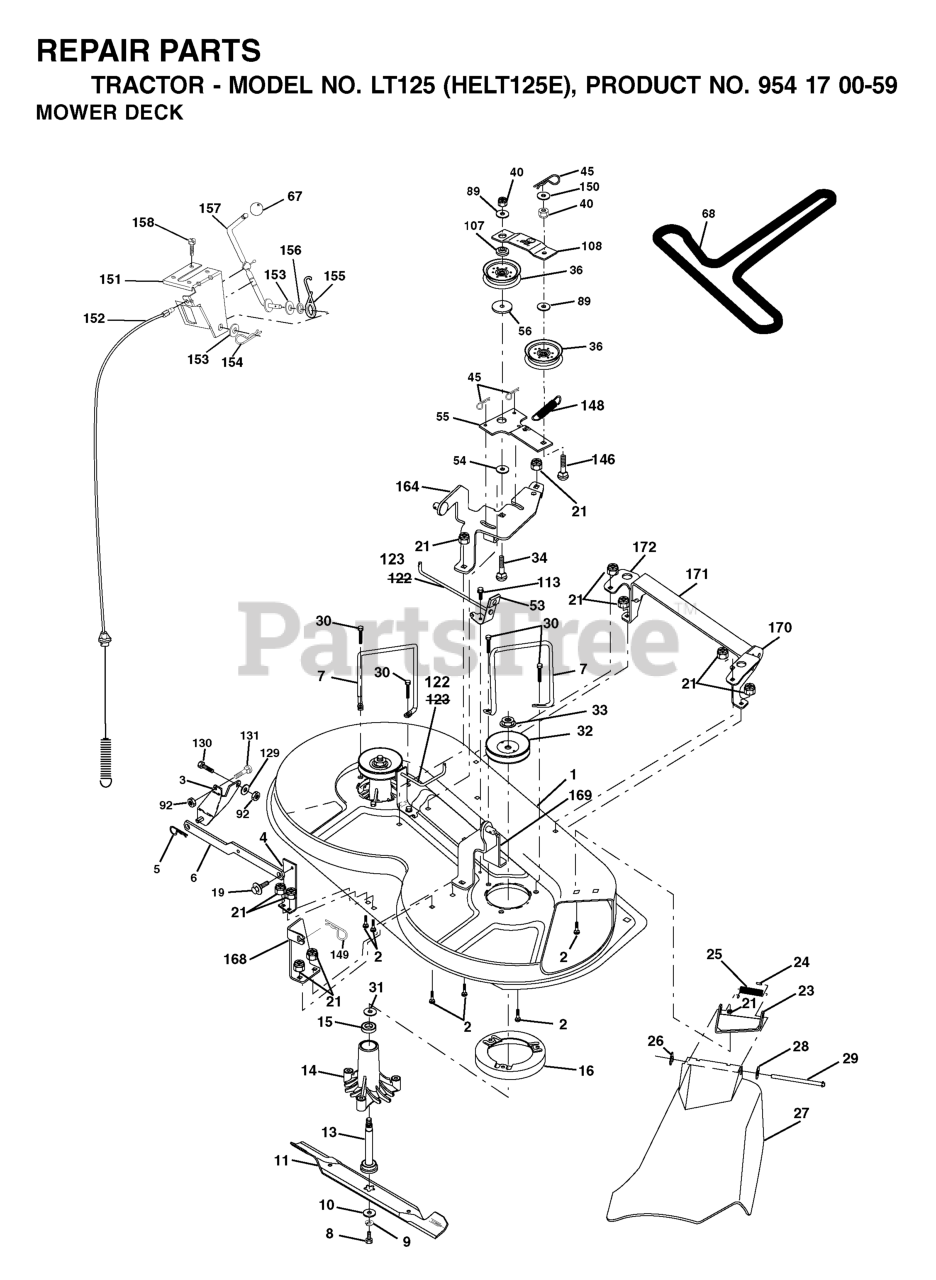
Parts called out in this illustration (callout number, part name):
2	RP BOLT 5/16-18 X3/4 ZN/YEL GR
3	BRKT ASM SWAY BAR
5	RETAINER-SPRNG RB
6	BAR SWAY DECK
8	BLADE BOLT
9	LOCKWASHER
10	WASHER.BLADE
11	BLADE, HI-LIFT 36" PREMIUM
13	SHAFT ASM VENT
14	HOUSING.MANDREL.VENTED (MACHD)
16	STRIPPER.MANDREL.ROUND.BLACK
19	BOLT SHD 5/16-18
21	LOCKNUT
23	BRACKET ASM DEFLECTOR
24	CAP-SLEEVE LT
25	SPRING TORSION
26	NUT PUSH M
27	CONSOLE.STLT.5SP.BLK
28	Washer 11/32 x 5/8 x 16 Ga SD
29	HINGE ROD
30	SCREW, WASHER HEAD
31	WASHER
32	PULLEY, MANDREL
33	NUT, FLG TOPLOCK 9/16"
36	FLAT IDLER PULLEY
45	RETAINER M
53	BRAKE ASSEMBLY
54	HARDENED WASHER
56	SPACER.RETAINER.MOWER
67	KNOB T (3/8 HOLE)
68	V-BELT.MOWER.
69	COTTER PIN
89	WASHER GT
92	NUT
107	SPACER.IDLER.ARM
108	STIFFENER.IDLER.ARM
113	Screw 5/16-18 x 1/2 Hex, Self Tapping 5/16-18 x 1/2
129	WASHER
131	BOLT D
146	BOLT, CARRIAGE IDLER
148	IDLER RETURN SPRING
149	SPRING.RETAINER.YELLOW.ZINC
151	BRACKET.CLUTCH.CABLE
153	WASHER FLAT 3/8"
154	SPRING RETAINER
155	SPRING RETENTION LEVER
156	SPACER.CLUTCH.CABLE
157	ROD CLUTCH CABLE 3/8"
158	SCREW
171	BRACE.SUPT.SUSP.FRT.CRD
